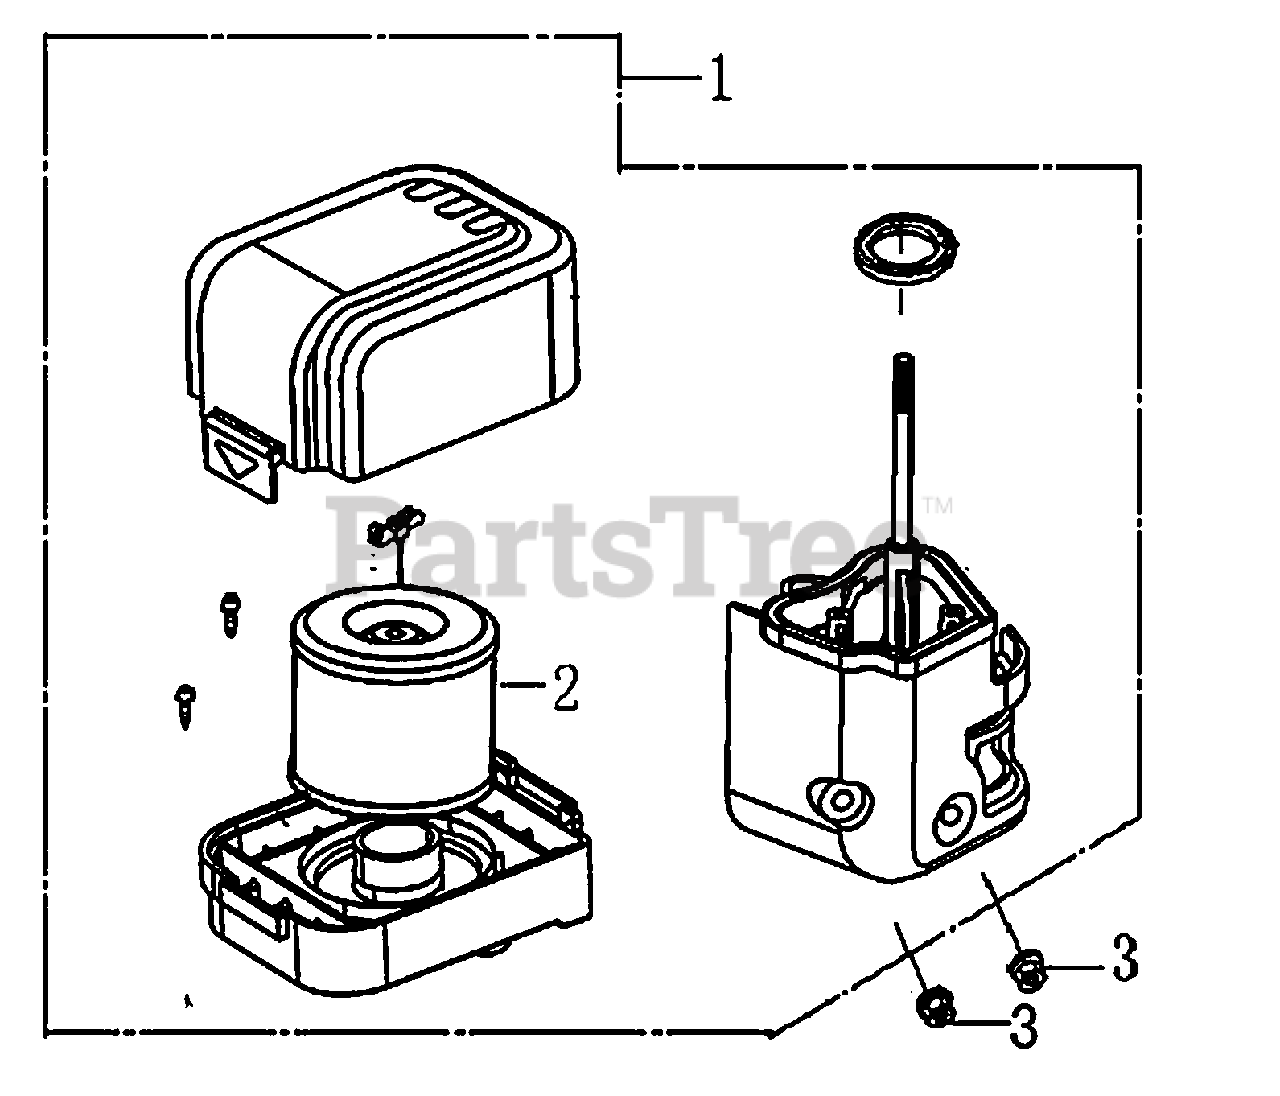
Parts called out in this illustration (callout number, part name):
1	AIR CLEANER ASSY
2	ELEMENT ASSY., AIR CLEANER
3	NUT, FLANGE, 6MM
